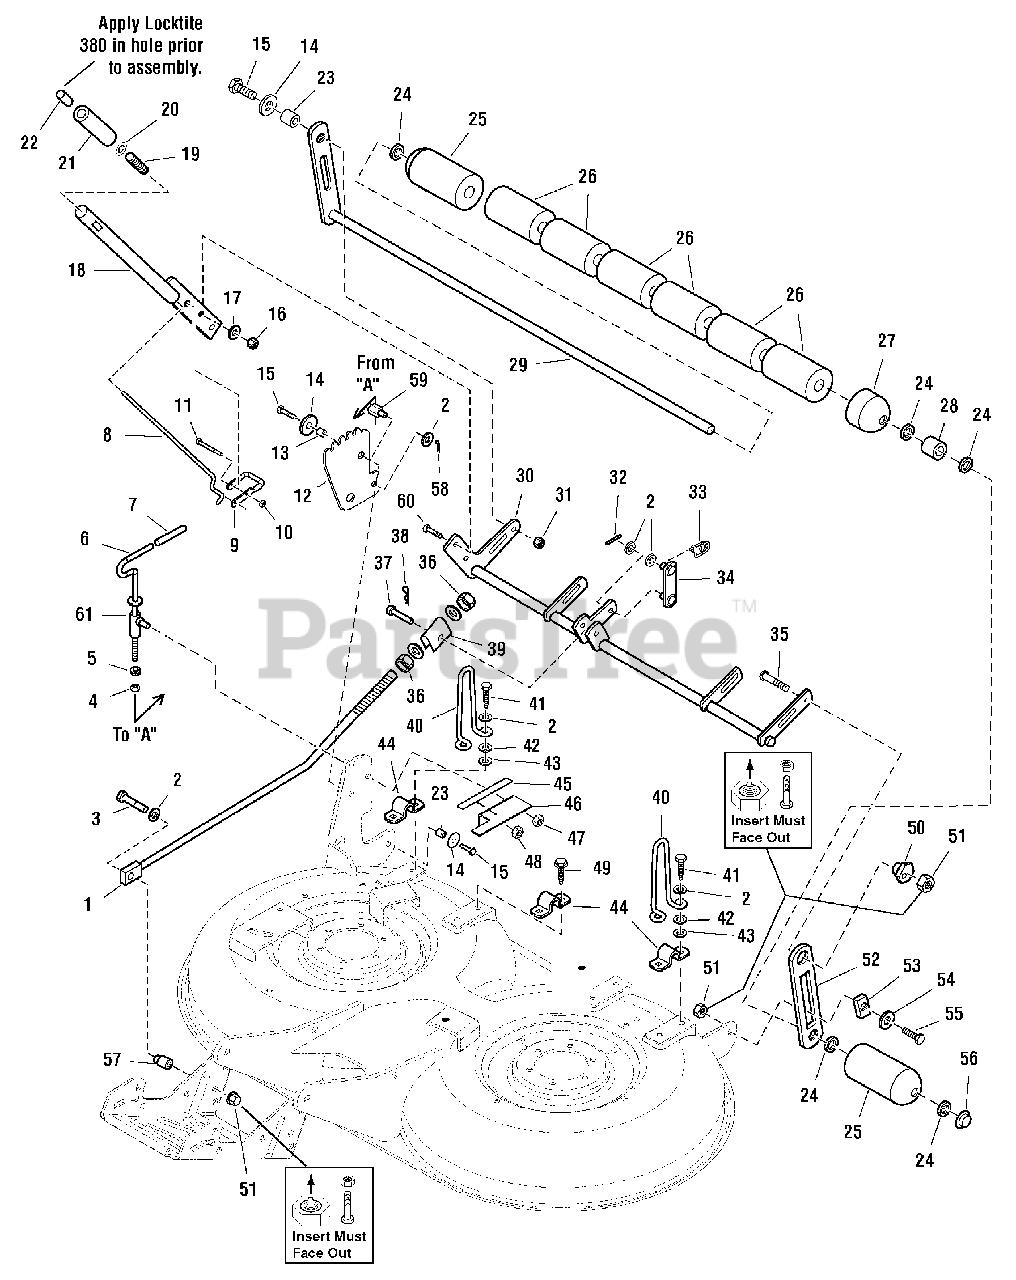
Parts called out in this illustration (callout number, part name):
1	ROD
2	WASHER, 3/8
3	CAPSCREW, Hex Head, 3/8-16 x 1 3/4
4	NUT, Hex Jam, 3/8-16
5	NUT, Hex Flange, 3/8-16 Black
6	ROD & WASHER ASSEMBLY, Adjust Handle
7	GRIP, Black Vinyl For Rod
8	ROD, Latch
9	LATCH, 5/16 WIRE
10	NUT, Hex Lock Esna Light, 1/4-20
11	CAPSCREW, Hex Head, 1/4-20 x 2 1/4
12	BRACKET, Adjusting
13	SPACER
14	WASHER, 5/16
15	CAPSCREW, Hex Head, 5/16-18 x 1 1/4
16	NUT, Hex 5/16-18
17	LOCKWASHER, Spring 5/16
18	HANDLE ASSEMBLY, Lift, 40" Munching
19	SPRING, Compression 3-7/8" Long
20	PUSH NUT, 1/4
21	GRIP, Black Soft for Rod
22	BUTTON, Red
23	SPACER
24	WASHER, 5/8
25	ROLLER
26	ROLLER
27	ROLLER
28	SPACER
29	SHAFT & BAR ASSEMBLY
30	SHAFT ASSEMBLY
31	NUT, Hex, 5/16-18
32	NUT, Hex Jam, 5/16-18
33	TRUNNION
34	ROD, Height Adjustment
35	CARRIAGE BOLT, 3/8-16 x 1-1/2
36	NUT, Hex, 5/8-11
37	PIN
38	CLIP, Hair Pin
39	TRUNNION, Rod
40	UPSTOP
41	CAPSCREW, Hex Head Taptite, 5/16-18 x 1-1/4
42	WASHER, 5/16
43	NUT, Push, 5/16
44	STRAP, Roller Support
45	DECAL, Height of Cut
46	BRACKET, Height of Cut
47	NUT, Hex Centerlock 3/8-16
48	NUT, Hex Flange Lock, 5/16-18
49	CAPSCREW, Taptite Hex Washer Head, 5/16-18 x 3/4
50	NUT, Hex Adjusting
51	NUT, Toplock Spiral Flange, 3/8-16
52	BAR
53	SLIDE
54	WASHER, 1/2
55	BOLT, Shoulder, 3/8-16 x 1-11/32
56	NUT, Push 5/8
57	SPACER
58	PIN, Cotter
59	PIVOT, 3/4 Hex
60	BOLT, Carriage, Short Neck, 5/16-18 x 1
61	GUIDE ASSEMBLY, Rod
